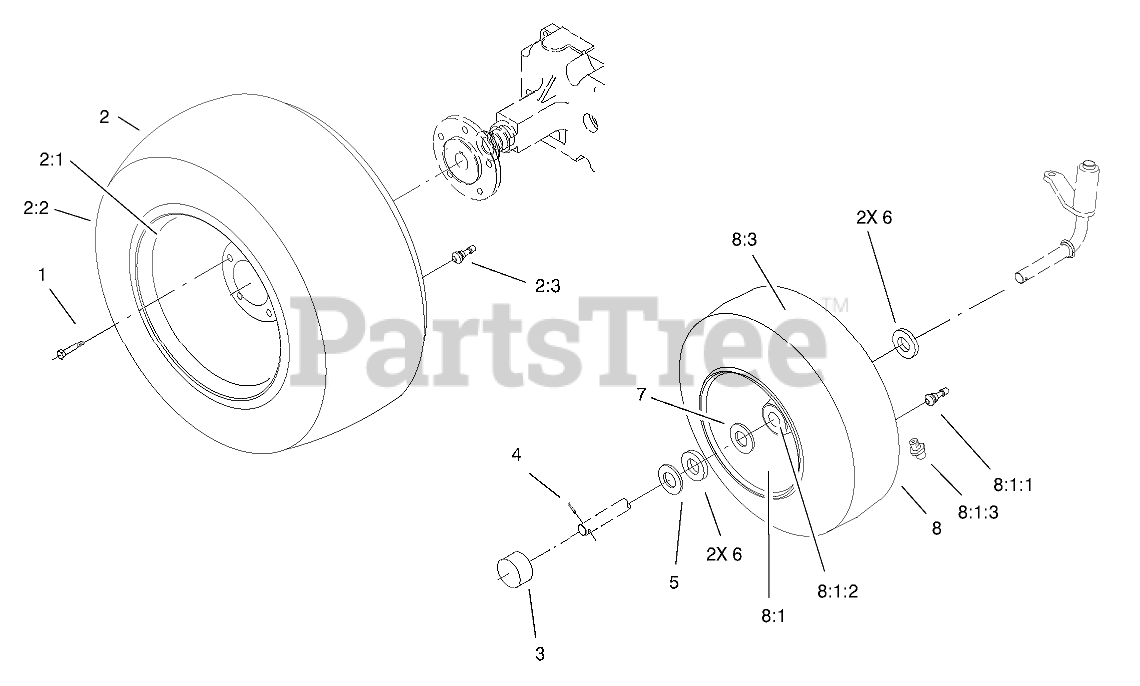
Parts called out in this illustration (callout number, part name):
1	BOLT-LUG
2	Tire ASM
2:1	WHEEL
2:2	TIRE
2:3	VALVE
3	CAP-HUB
4	PIN-COTTER
5	WASHER-PLAIN
6	WASHER
7	WASHER-SHIM
8	Front Wheel ASM
8:1	Wheel ASM
8:1:1	VALVE
8:1:2	BEARING-WHEEL
8:1:3	ZERK-GREASE
8:3	Tire (16 x 6.5-8) 2-Ply -2 Wheel Axel
